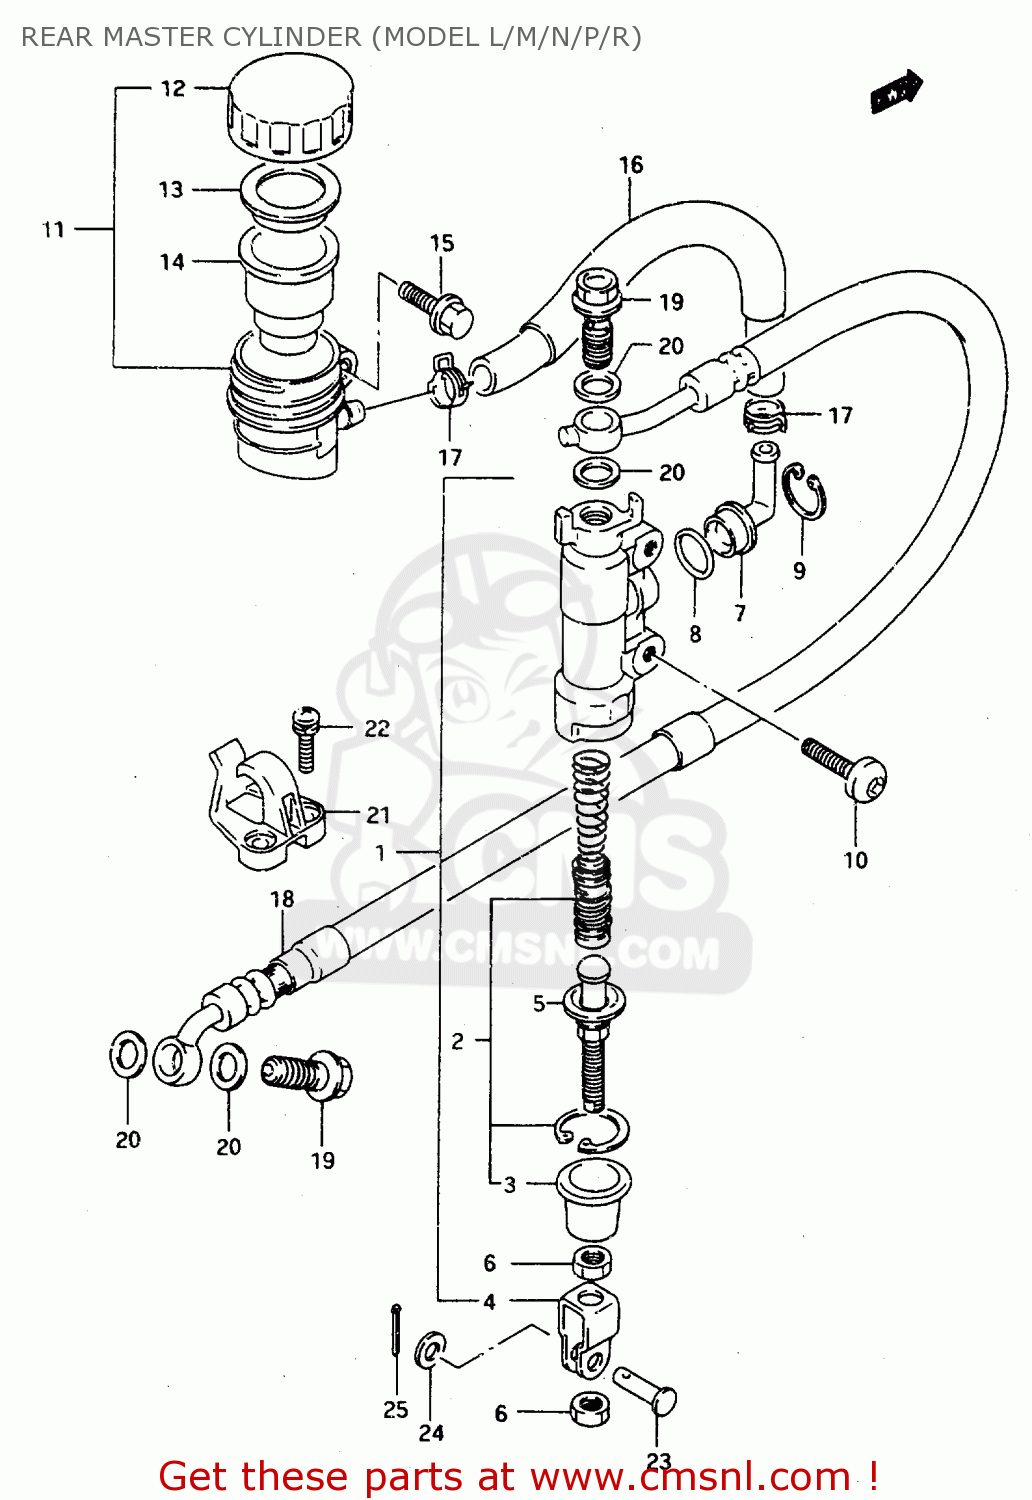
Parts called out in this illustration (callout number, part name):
1	CYLINDER ASSY, REAR MASTER
2	PISTON/CUP SET
3	BOOT
4	YOKE
5	ROD,PUSH
6	NUT
7	CONNECTOR
8	O RING
9	CIRCLIP
10	SCREW
11	TANK ASSY,RR BRAKE RESERVOIR
12	CAP
13	PLATE
14	DIAPHRAGM
15	BOLT
16	HOSE,RESERVOIR TANK
17	CLAMP,RESERVOIR HOSE
18	HOSE,RR BRAKE
19	BOLT UNION
20	WASHER(10X15X1.5)
21	GUIDE,RR BRAKE HOSE
22	SCREW
23	PIN
24	WASHER
25	PIN
